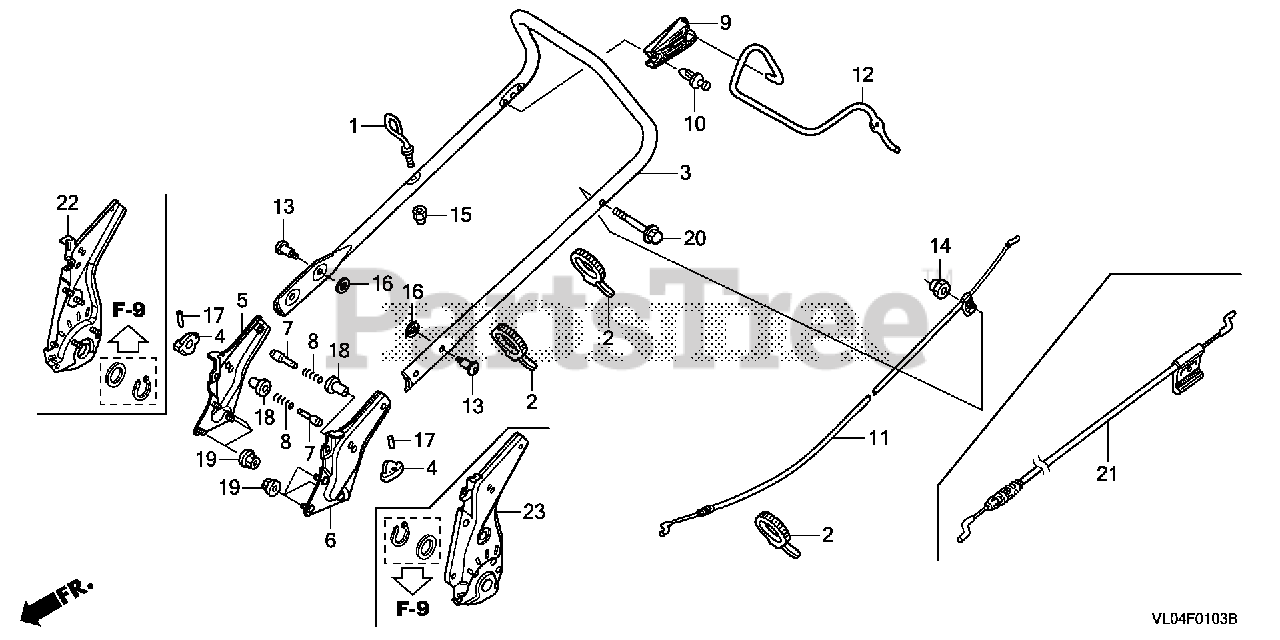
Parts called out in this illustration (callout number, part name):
1	GUIDE, ROPE
2	TIE, CABLE (157.5MM)
3	PIPE, HANDLE *NH105* (MAT BLACK)
4	GRIP, HANDLE JOINT *NH164* (GRIP GRAY)
7	PIN (8MM)
8	SPRING, HANDLE ADJUSTING
9	STOPPER, LEVER
12	LEVER, BRAKE *NH105* (MAT BLACK)
13	BOLT, SPECIAL (8X32)
14	NUT, NYLON LOCK (6MM)
15	NUT, NYLON LOCK (6MM)
16	WASHER (25MM)
17	PIN, COILED (2X12)
18	COLLAR, HANDLE HEIGHT ADJUSTING
19	NUT, FLANGE (8MM)
20	BOLT, FLANGE (6X45)
21	CABLE, BRAKE
22	STAY, R. HANDLE
23	STAY, L. HANDLE
